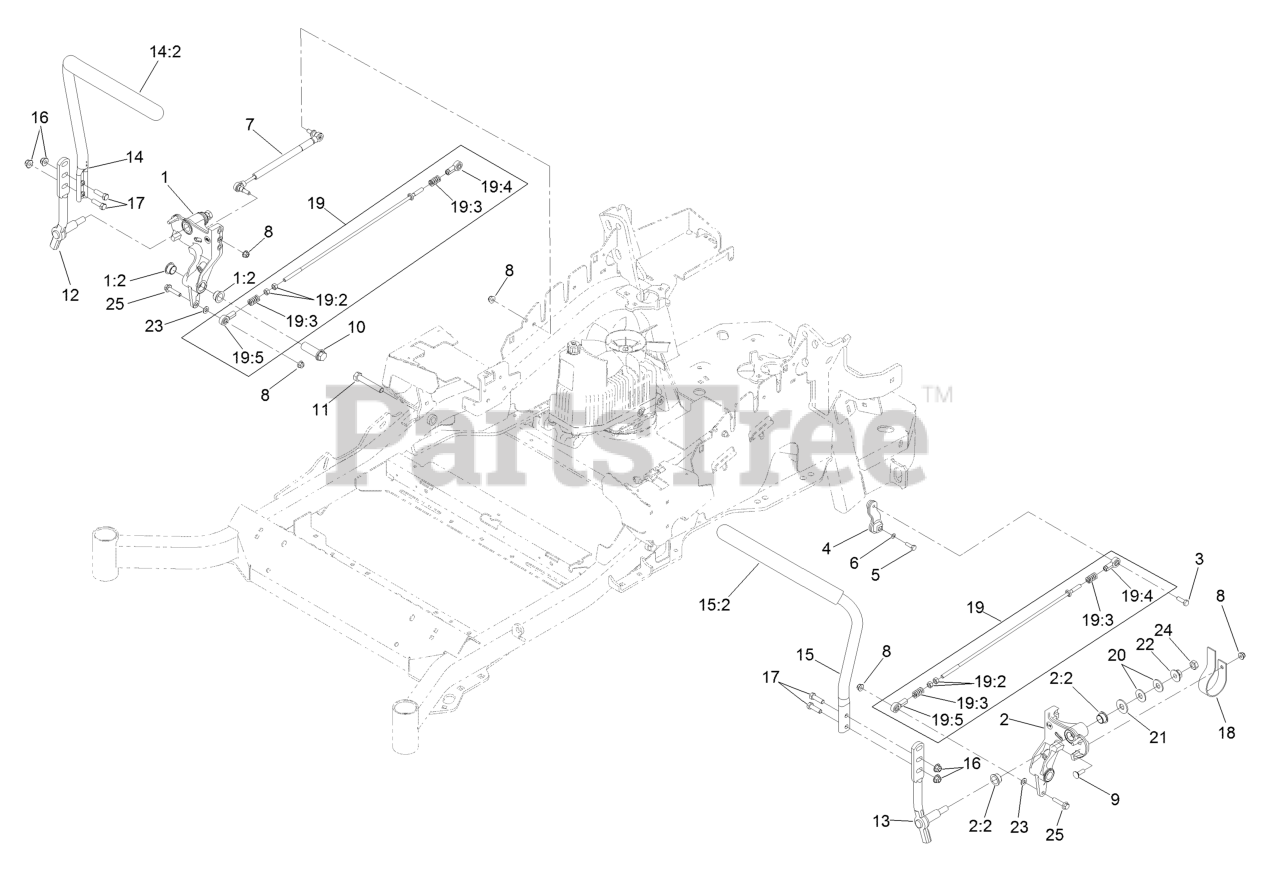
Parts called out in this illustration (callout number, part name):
1	RH MOTION CONTROL AND BUSHING ASM
1:2	BUSHING-FLANGE
2	LH MOTION CONTROL AND BUSHING ASM
2:2	BUSHING-FLANGE
3	SCREW-HH, THREAD LOCKING
4	ARM-CONTROL, PUMP
5	SCREW-HH
6	WASHER-SPRING
7	DAMPER-CONTROL, MOTION
8	NUT-HF, NI
9	BOLT-CARR
10	HUB-THREADED
11	SCREW-HH
12	LEVER-CONTROL MOTION, RH
13	LEVER-CONTROL MOTION, LH
14	RH STEERING HANDLE ASM
14:2	GRIP-LEVER, CONTROL
15	LH STEERING HANDLE ASM
15:2	GRIP-LEVER, CONTROL
16	NUT-HF, NI
17	SCREW-HH
18	SPRING-LEAF
19	FRONT PUMP LINKAGE ASM
19:2	NUT-HEX
19:3	SPRING-COMPRESSION
19:4	BALLJOINT-LH
19:5	BALLJOINT-RH
20	WASHER-SPRING
21	WASHER-FLAT
23	WASHER-PLAIN
24	NUT-JAM
25	SCREW-HHF
